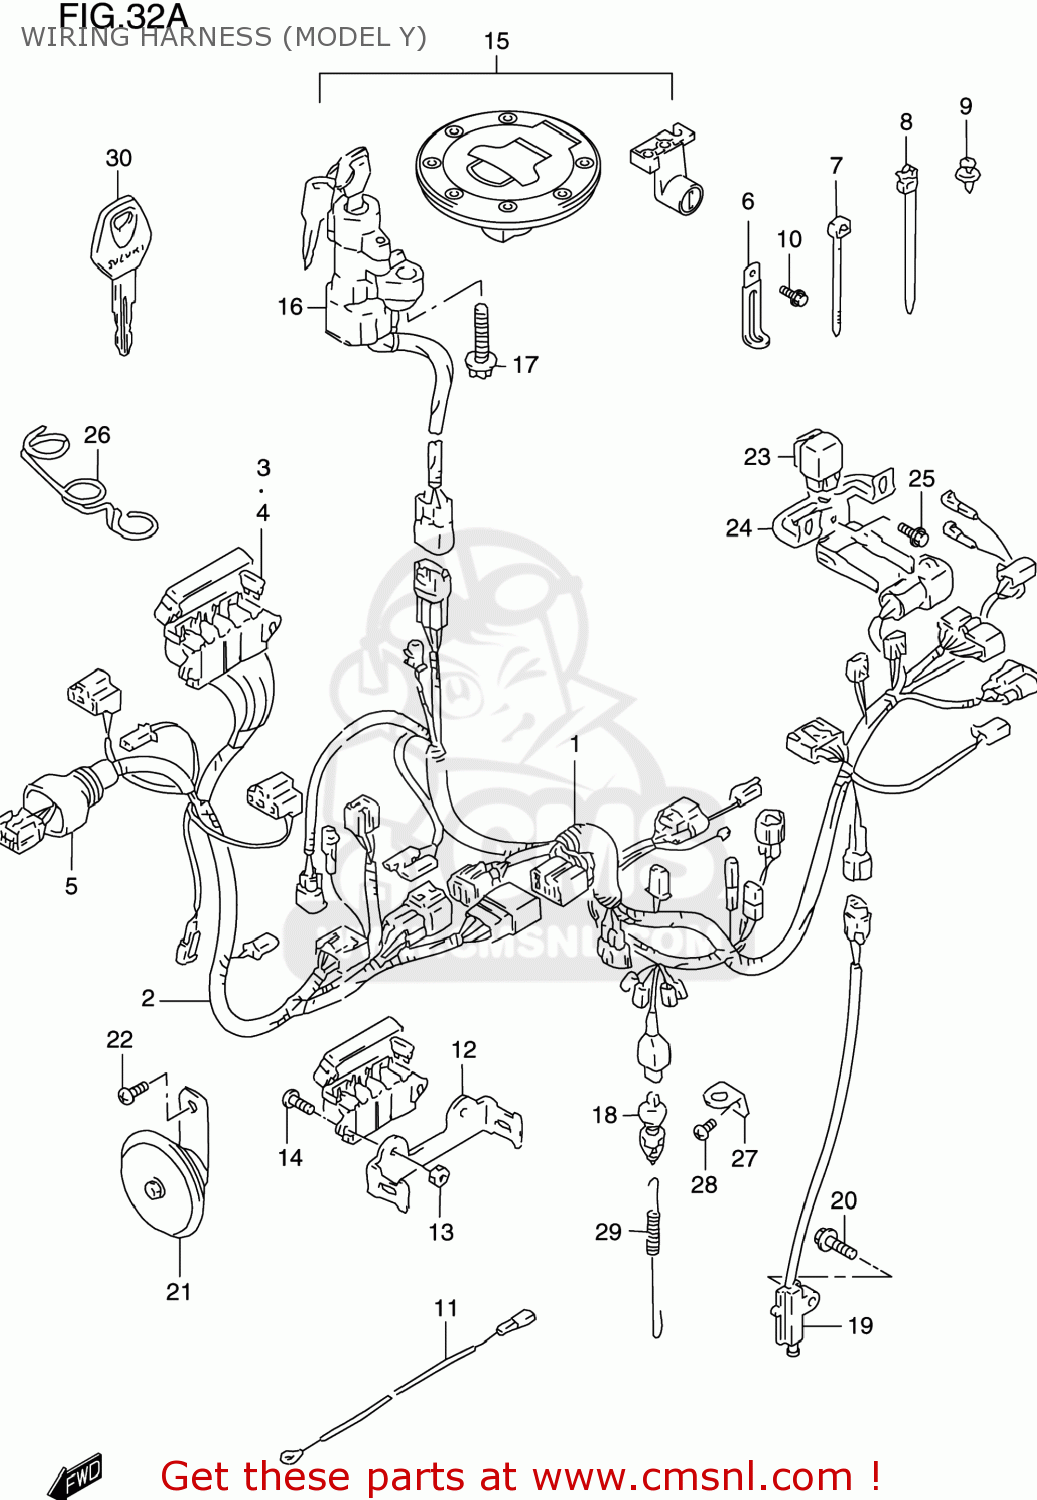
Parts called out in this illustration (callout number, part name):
1	HARNESS,WIRING NO.1
2	HARNESS,WIRING NO.2
3	FUSE(10A)
4	FUSE(15A)
5	COVER,SPEEDOMETER COUPLER
6	CLAMP(L:65)
7	CLAMP(L:125)
8	CLAMP
9	CLIP(BLACK)
10	BOLT
11	WIRE,OIL PRESSURE SWITCH LEAD
12	BRACKET,FUSE BOX
13	NUT,COWLING SCREEN
14	SCREW 5X12
15	LOCK SET
16	LOCK ASSY,STEERING
17	BOLT(8X20)
18	SWITCH ASSY,STOP LAMP
19	SWITCH ASSY,SIDE STAND
20	BOLT
21	HORN ASSY
22	SCREW(8X14)
23	RELAY ASSY
24	BRACKET,SIDE STAND RELAY
25	BOLT
26	GUIDE,WIRING HARNESS
27	BRACKET,STOP LAMP SWITCH
28	SCREW
29	SPRING
30	KEY,BLANK
